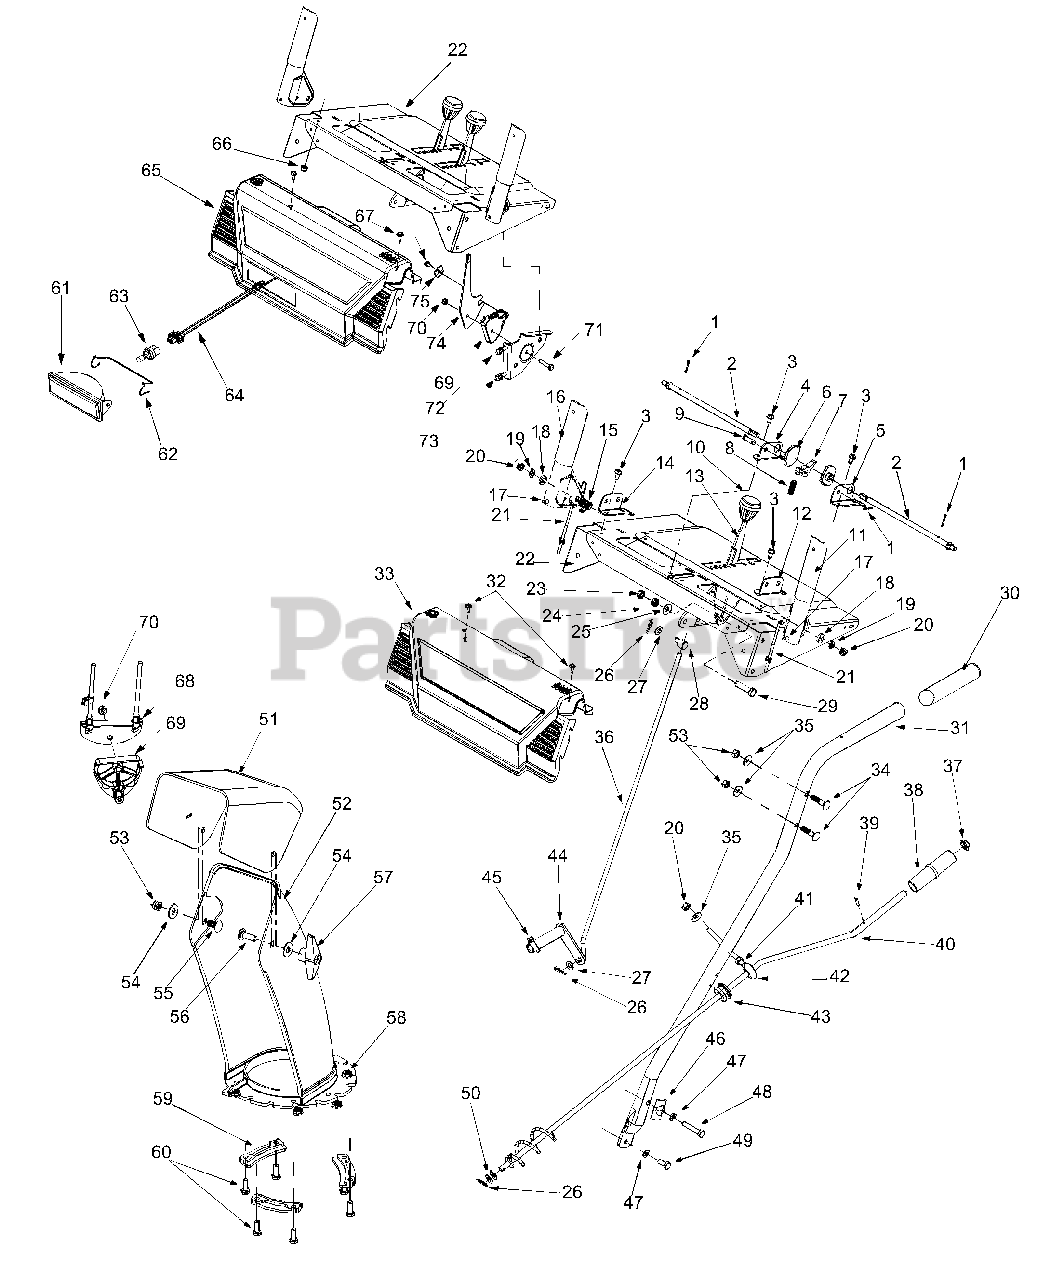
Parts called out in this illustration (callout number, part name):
1	Cotter Pin
3	Hex Washer Screw 1/4-20 x .5
4	Handle Support Bracket - RH
5	Handle Support Bracket - LH
6	Cam Lock Handle
7	Handle Lock Pawl
8	Compression Spring
9	Clevis Pin
11	Handle Assy - LH
13	Shift Handle
14	Handle Support Bracket - RH
15	Torsion Spring
16	Handle Assy - RH
17	Rubber Bumper
18	Washer
19	Lock Washer 5/16
20	Hex Nut 5/16-18
21	Cable
23	Jam Lock Nut 3/8-24
24	Compression Spring
25	Bell Washer
26	Cotter Pin
27	Flat Washer 5/16
28	Ferrule
29	Hex Cap Screw 3/8-24 x 1.50
31	Handle -LH
31	Handle -RH
32	Hex Washer Screw
33	Handle Panel
33	Handle Panel w/ Top Light
34	Carriage Bolt 5/16-18 x 1.50
35	Bell Washer .340 ID x .872 OD
36	Shift Rod
37	Push Cap
38	Chute Knob
39	Roll Pin
40	Chute Crank
42	Chute Crank Eyebolt
43	Rubber Grommet
44	Shift Arm Assembly
45	Hex Washer Screw 1/4-20 x 1.0
46	Handle Tab
47	Lock Washer 5/16
48	Hex Cap Screw 5/16-18 x 1.75
49	Hex Cap Screw 5/16-18 x .75
50	Flat Washer
51	Upper Chute
52	Lower Chute
53	Hex Lock Nut 5/16-18
54	5/16 Washer
55	Carriage Bolt 5/16-18 x .75
56	Carriage Screw 5/16-18 x 1.0
57	Knob
58	Hex Lock Nut 1/4-20
59	Flange Keeper
60	Hex Cap Screw 1/4-20 x .75
61	Lens Housing Assembly
62	Headlight Retaining Wire
63	Halogen Light
64	Light Harness
65	Panel w/ Light
66	Hex Nut 1/4-20
67	Hex Washer Screw #10-16 x .625
69	Chute Tilt Cable Guide
70	Lock Nut
71	Hex Bolt 5/16-18 x 1.5"
72	Chute Control Cable
73	Chute Deflector Control Cable w/Clip
74	Chute Tilt Handle
75	Special Washer
76	AB Screw 1/4-14 x 0.625"
